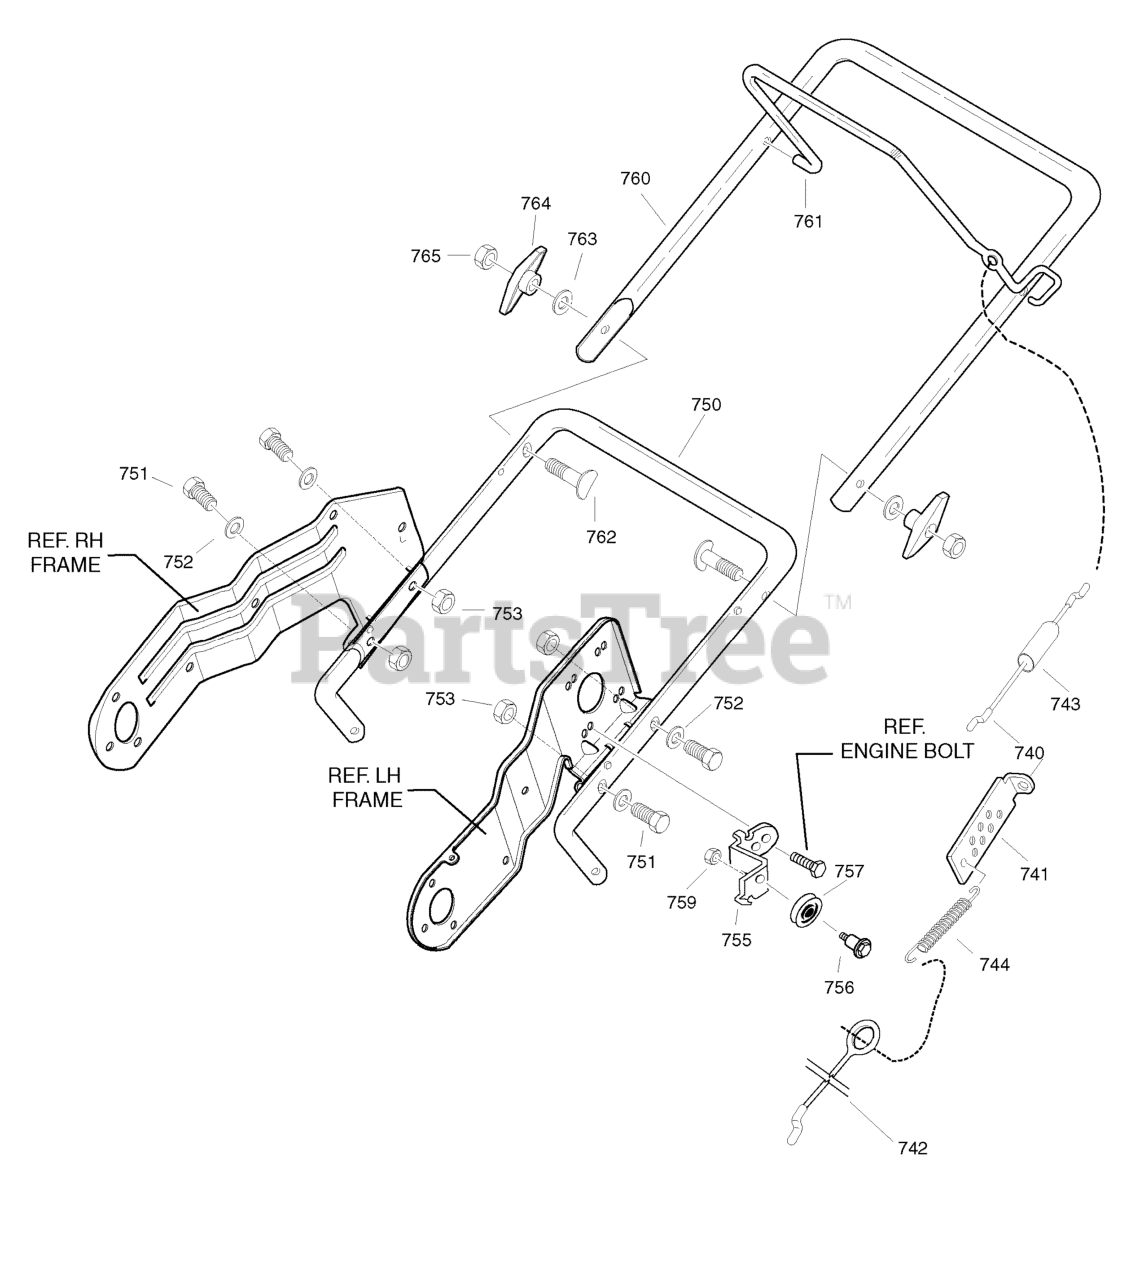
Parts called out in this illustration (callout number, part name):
740	CABLE, UPPER
741	BRACKET, CABLE ADJUST
742	CABLE, LOWER CONTROL
743	BOOT, CLUTCH SPRING
744	SPRING, EXTENSION
750	HANDLE, LOWER
751	SCREW, 1/4-20 X 1.25
752	WASHER, FLAT
753	NUT, 1/4-20
755	BRACKET, CABLE
759	NUT, 1/4-20 YZ
760	UPPER HANDLE
761	BAIL, CONTROL
763	WASHER, FORM
764	KNOB, T 3.00 WD
765	NUT, 5/16-18
